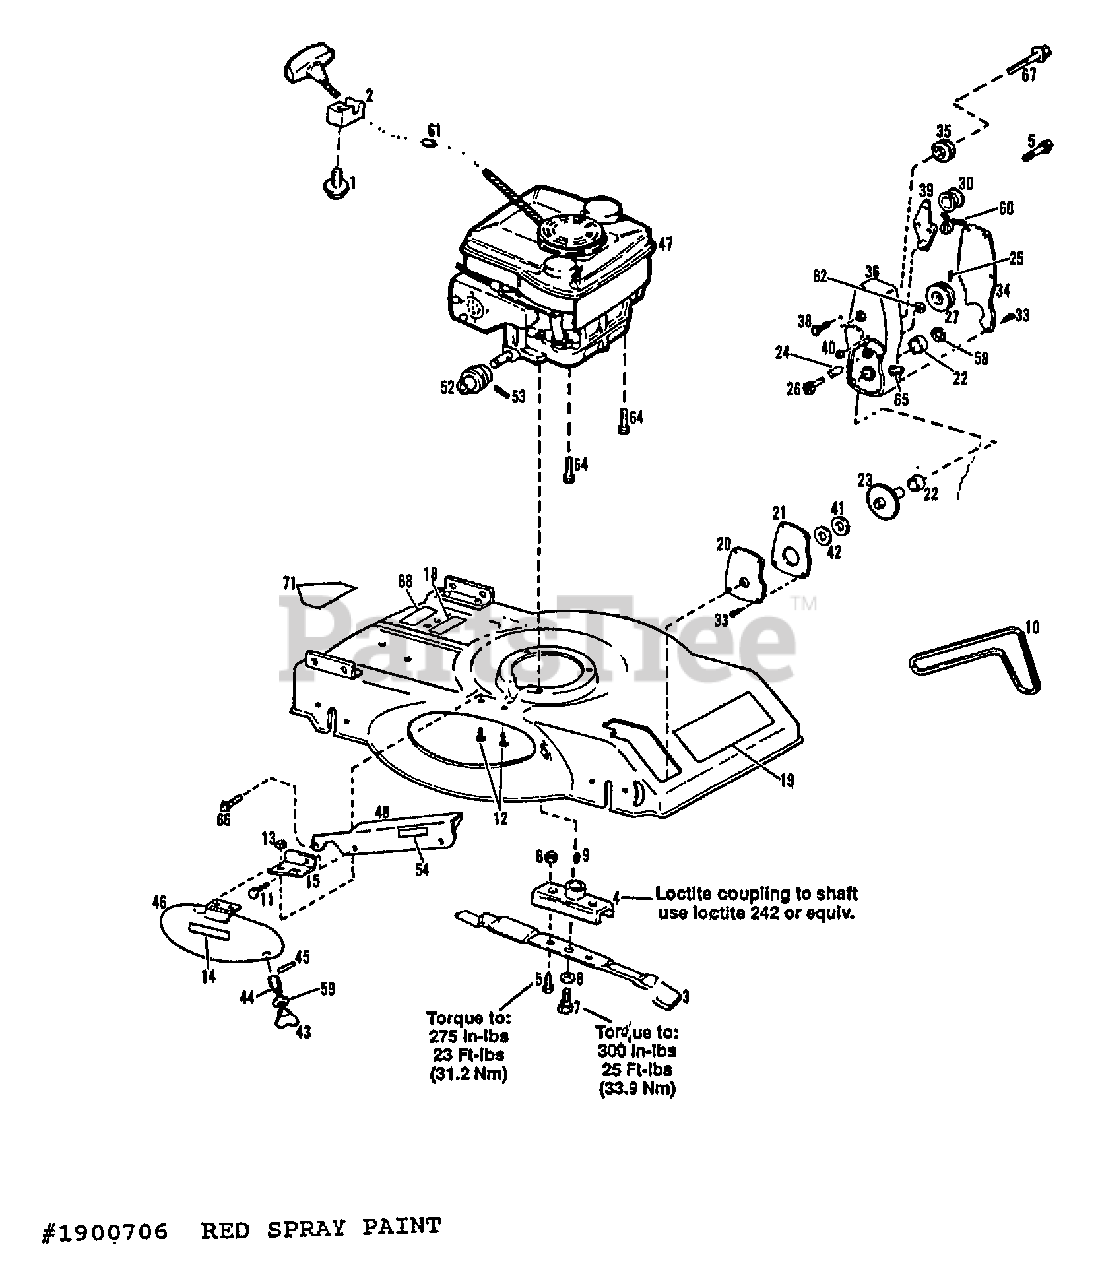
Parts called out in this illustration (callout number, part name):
1	SCR-HFLK 1/4-20X1.0 THFRM {NOT 8656R}
2	GUIDE-ROPE {NOT 8656R}
3	BLADE-22" MULCHER
4	ASSM-BLADE COUPLING
5	SCR-HH 3/8-16X1.0 G5 ZP
6	NUT-LOCK 3/8-16
7	SCR-SHOULDER
8	WASHER-LK .5
9	KEY-WOODRUFF
10	BELT-DRIVE
11	SCR-SHOULDER
12	SCR-CARR 1/4-20X.375
13	NUT-HF/LK 1/4-20 ZP
14	DECAL-CAUTION
15	BRKT-SUPPORT
18	DECAL-CUTTING HEIGHT
19	DECAL-LOGO MULCHER 22"
20	COVER-GEAR CASE BOTTOM
21	GASKET-GEAR CASE
22	BEARING-BRONZE
23	ASSM-GEAR SHAFT
24	BEARING-BRONZE
25	PIN-DRIVE .218X1.12
26	ASSM-STEEL PINION SHAFT
27	SHEAVE
30	IDLER-FLAT
33	SCR-HW M10-24X.5 STH ZP
34	COVER-GEAR CASE TOP
35	SHEAVE
36	ASSM-GEAR CASE
38	SCR-SHOULDER
39	ASSM-IDLER ARM
40	NUT-PUSH 3/8 ZP
41	WASHER-1.5X.755X.062
42	WASHER-FELT
43	PIN-CHUTE LOCK
44	SPRING-COMPRESSION
45	PIN-ROLL .093 DIAX.62
46	COVER-DISCHARGE W/DECAL (INCL. 12-14,43-45, 59)
47	B & S ENG, 4.0 HP #122782 RCL STRT (8654R MDL)
47	B & S ENG. 5.0 HP #124782 RCL STRT (8655R MDL)
47	B & S ENG, 5.0 HP #124787 ELEC STR (8656R MDL)
48	ASSM-BELT COVER
52	SHEAVE
53	PIN-ROLL
54	DECAL-FRONT WHEEL DRIVE
58	RING-GRIP EXT .5 ID
59	WASHER-.75X.312X.065 ZP
60	SPRING-TORSION
61	STOP-STARTER ROPE {NOT 8656R}
62	WASHER-SHIM
64	SCR-HH 3/8-16X1.0 THDFM
65	FITTING-GREASE 1/4-28X2.00
66	SCR-FLANGE 1/4-20X3/4 GR5
67	SCR-HH 5/16-18X.875 G5 ZP
68	DECAL-U.S.A.
71	DECAL-OPEI CAUTION {NOT 8656R}
